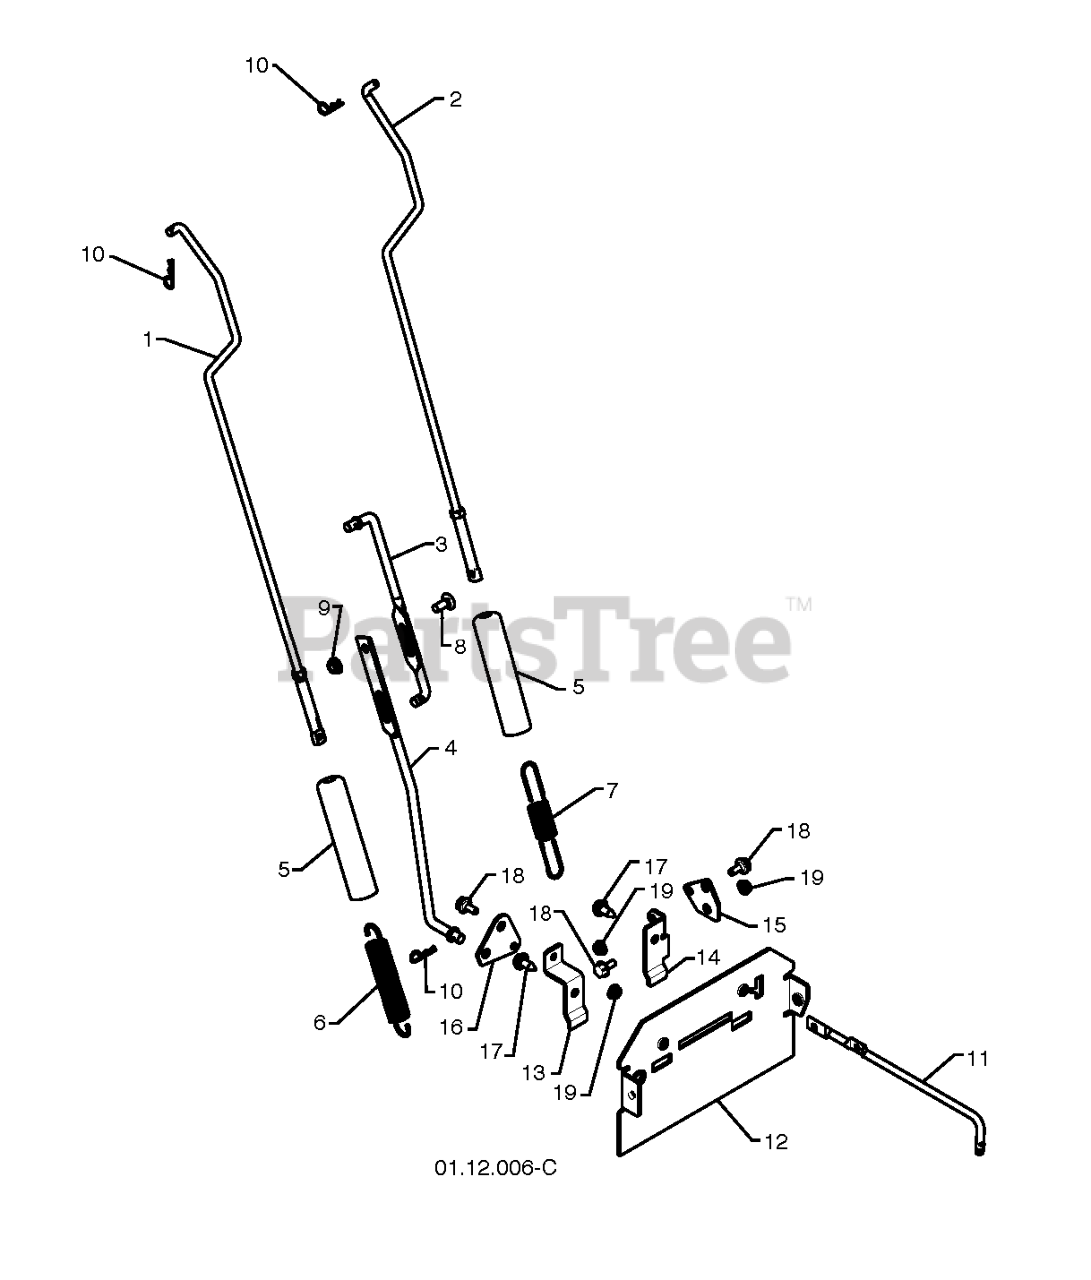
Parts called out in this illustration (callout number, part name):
1	ROD.ASM.IMPELLER
2	ROD.ASM.TRACTION
3	ROD, UPPER SPEED CONTROL
4	ROD, LOWER SPEED CONTROL.SNOW
5	SLEEVE, SPRING
6	SPRING, AUGER CONTROL
7	SPRING, TRACTION DRIVE
8	BOLT
9	NUT.FLANGE.5/16
10	SPRING RETAINER
11	ROD.CLUTCH.YELLOW.ZINC(VT)
12	PLATE.REAR.SNOW.PNT.ORANGE
13	BRACKET.SHIFTER.PLATE.BZP
14	BRACKET.CLUTCH.PLATE.BZP
15	PLATE.CLUTCH.BZP
16	PLATE.SHIFTER.BZP
17	SCREW
18	BOLT.SHOULDER.3/X.25
19	NUT.HEX.FLANGE.1/4
